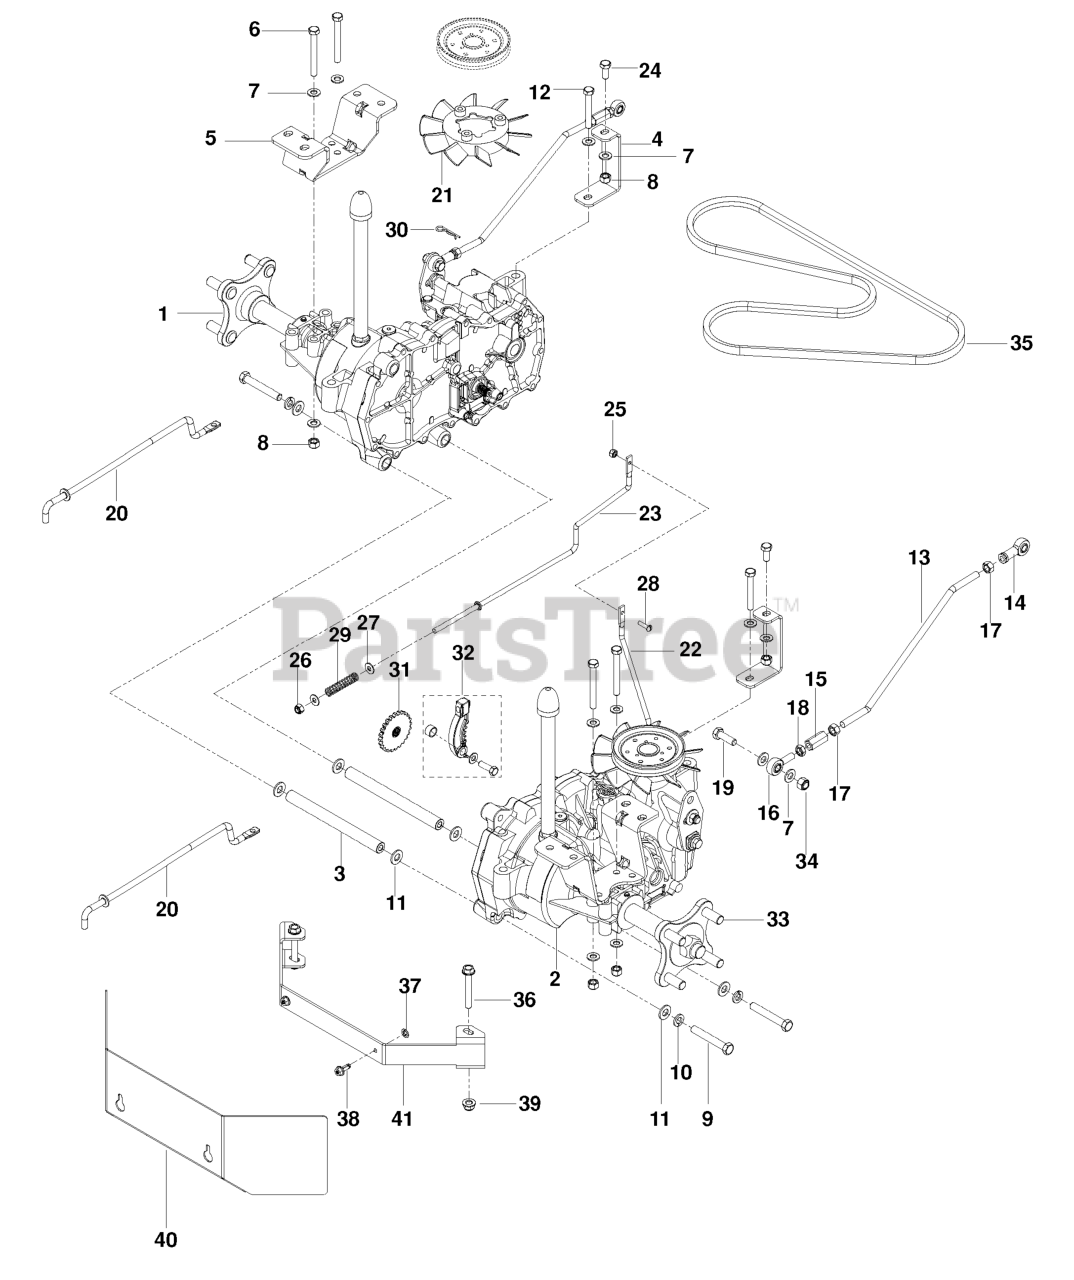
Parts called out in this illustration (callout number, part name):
1	HG_EZT, LT
2	HG_EZT, RT
3	SPACER TUBE, EZT
4	SUPPORT.FRONT.TRANS.BLACK.
5	EZT MOUNT, REAR, BLACK
6	HCS 5/16C X 2-3/4
7	FLAT WASHER 5/16 SAE
8	NUT 5/16 NYLOC
9	HCS 3/8C X 2 1/2
10	SLW 3/8 STD
11	WASHER 3/8 SAE FLAT
13	RP.ROD, MOTION CONTROL
14	RH ROD END
15	ROD END COUPLER
16	RP.ROD.END.LH
18	NUT 5/16F LEFTHAND
19	HCS 5/16C X 1
20	LINKAGE, BYPASS, EZT
21	HG_HYDRO FAN 51365
22	LINKAGE.BRAKE.LT
23	LINKAGE, BRAKE RT
24	HCS 5/16C X 3/4
25	NUT 10-24 NYLOC
26	NUT.1/4-20.HEX.NYLOC.ZD
27	WASHER 1/4 SAE
28	SCR #10-24 X 3/4
30	HAIRPIN #2
31	HG_DISC COG BRAKE 51635
32	HG_KIT BRAKE ARM (EZT)
33	HUB KIT (H-G #70314)
34	5/16-18 THIN PROF NY
35	BELT, HYDRO PUMP
36	HHFS 5/16-18 X 2.25 GD 5
37	PALNUT 1/4
38	SCREW- 1/4-20 X 5/8
39	5/16-18 NYLOC FLANGE NUT
40	SHIELD, DRIVE PULLEY BLK
41	BRACKET, GUARD
